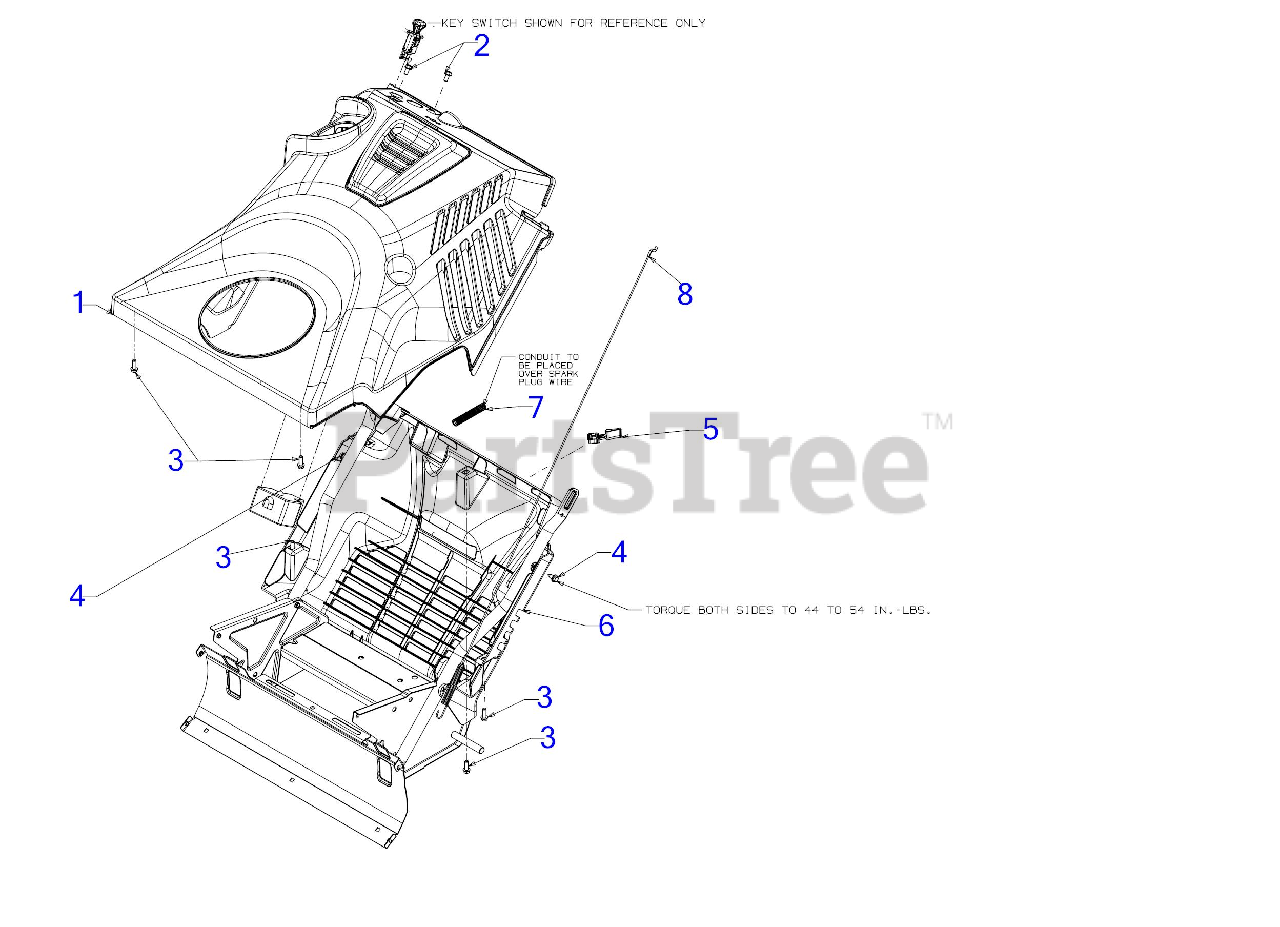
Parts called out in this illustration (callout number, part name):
1	COVER ASSEMBLY
2	HEX SCREW 1/4-15 x .50
3	SCREW 1/4-15 x .750
4	SCREW 1/4-20X.625
5	CHOKE EXTENION LEVER
6	BOTTOM COVER
7	CONVOLUTED CONDUIT
8	AUGER CLUTCH CABLE 37.05"
